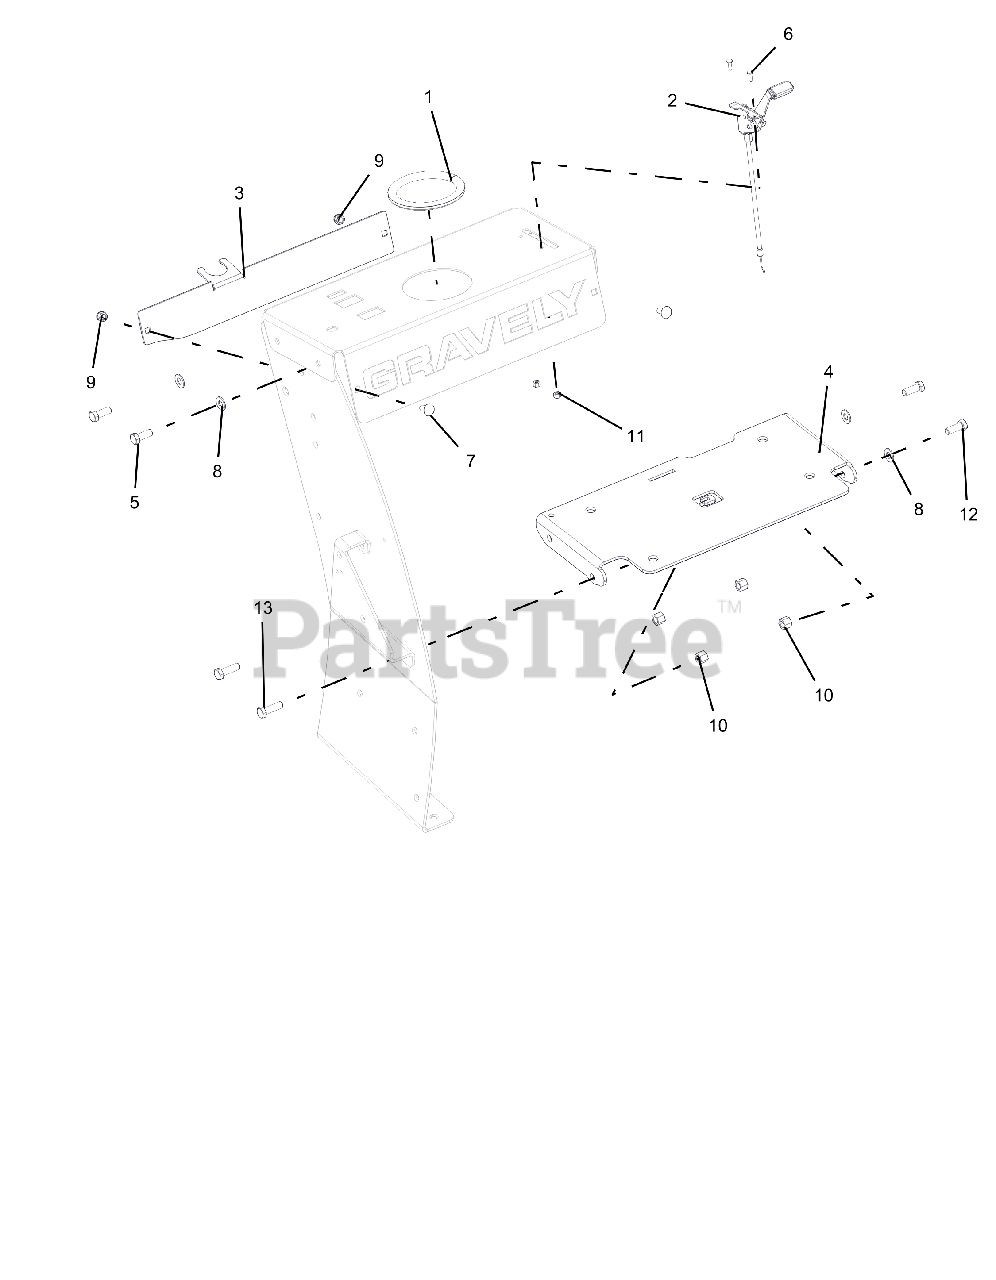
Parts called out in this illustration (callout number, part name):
1	TRIM, RUBBER DEGE 12"
2	CABLE, THROTTLE 49.5"
3	BRACKET, REMOTE ROV HYDRO-BLACK
4	BRKT, FUEL TANK GRAVELY
5	BLT-HEX .38-16X1.00 GR5 YWZC
6	SCR - PANHDPHLPS 8-32 X .5
7	BLT-RDHDSQNK .31-18X.75 G5 YWZC
8	WSHR-FL-STL.406X.812X.065 YWZ
9	NUT-LK-NYL .312-18 YWZC
10	NUT-LK-NYL .38-16 YWZC
11	NUT-LK-NYL #8-32 YWZC
12	BLT-HEX .38-16X1.00 GR5 YWZC
13	BLT-HEX .38-16X1.25 GR5 YWZC
